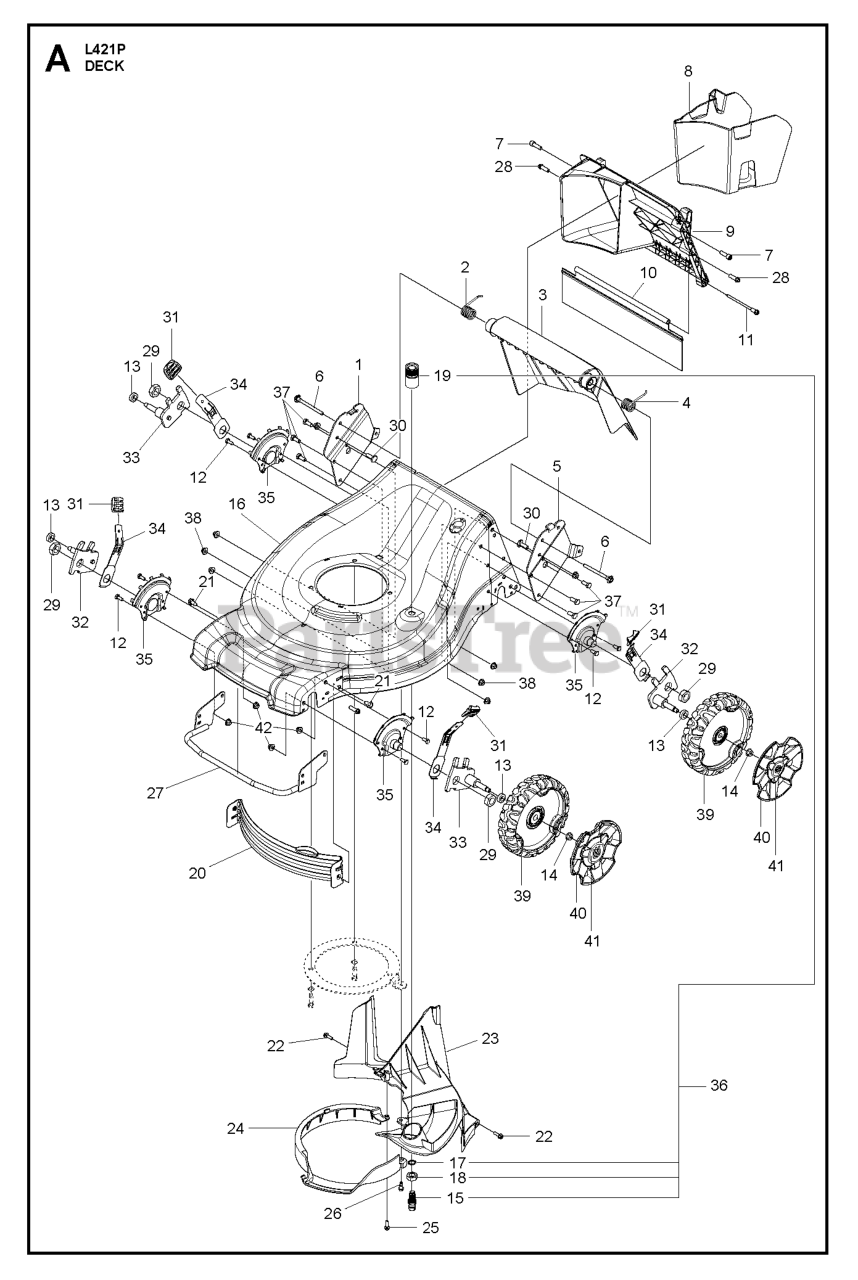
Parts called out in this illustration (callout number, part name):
1	HANDLE BRACKET RIGHT, 21 COMME
2	TORSION SPRING DOOR, RH, 21 CO
3	DOOR.REAR.21 EFF.GRY
4	TORSION SPRING DOOR, LH, 21 CO
5	HANDLE BRACKET LEFT, 21 COMMER
6	BOLT.DOOR.PIVOT..375-16.21EFF
7	SCREW.HI-LO,5/16-14 X T-45
8	PLUG.MULCH.21 EFF
9	INSERT.REAR.21 EFF
10	SKIRT.REAR.21 EFF
11	SCREW.HI-LO.5/16-14 X 4.10
12	BOLT
13	O-RING..070X.487.NEOPRENE
14	NUT.HEX.FLANGE.3/8-16.LO(3 2)
15	WASHOUT.PORT.ZINC.RGD.22+
16	HOUSING ASSY KIT 21EFF.COMM.66
17	WASHER.LOCK.INTERNAL.TOOTH
18	LOCKNUT.HEX.WITH.O-RING
19	COUPLING.QUICK CONNECT
20	BAFFLE.FRONT.21 EFF
21	BOLT.5/16HEX.WHS.HD
22	SCREW.HI-LO.13-16X.750.375XDRV
23	COVER.BELT/REAR BAFFLE.21 EFF
24	RING.STRIPPER.21 EFF
25	SCREW.HI-LO.13-16X.750.375XDRV
26	BOLT SHOULDER_1/4-20_TRILOB
27	BUMPER ASSY FRONT, 21 COMMERCI
28	SCREW.HI-LO,5/16-14 X T-45
29	NUT HEXAGON LOCK 3/4-16" GRA Z
30	BOLT.CARRIAGE.5/16-18
31	SELECTOR KNOB
32	ARM AXLE ARM ASSM, RF, LR, 21
33	AXLE AXLE ARM ASSM. LF,RR BLAC
34	SPRING.SELECT.4PT.21EFF.004
35	PLATE HEIGHT ADJUSTER PLATE AS
36	KIT.WASH-OUT.PORT
37	BOLT.FIN.HEX.5/16-18X3/4
38	NUTNYLOK.FLRANGE.5/16-18
39	WHEEL ASSY 210, IDLE, MEDIUM
42	NUT.FLANGE.1-4-20-SERR
